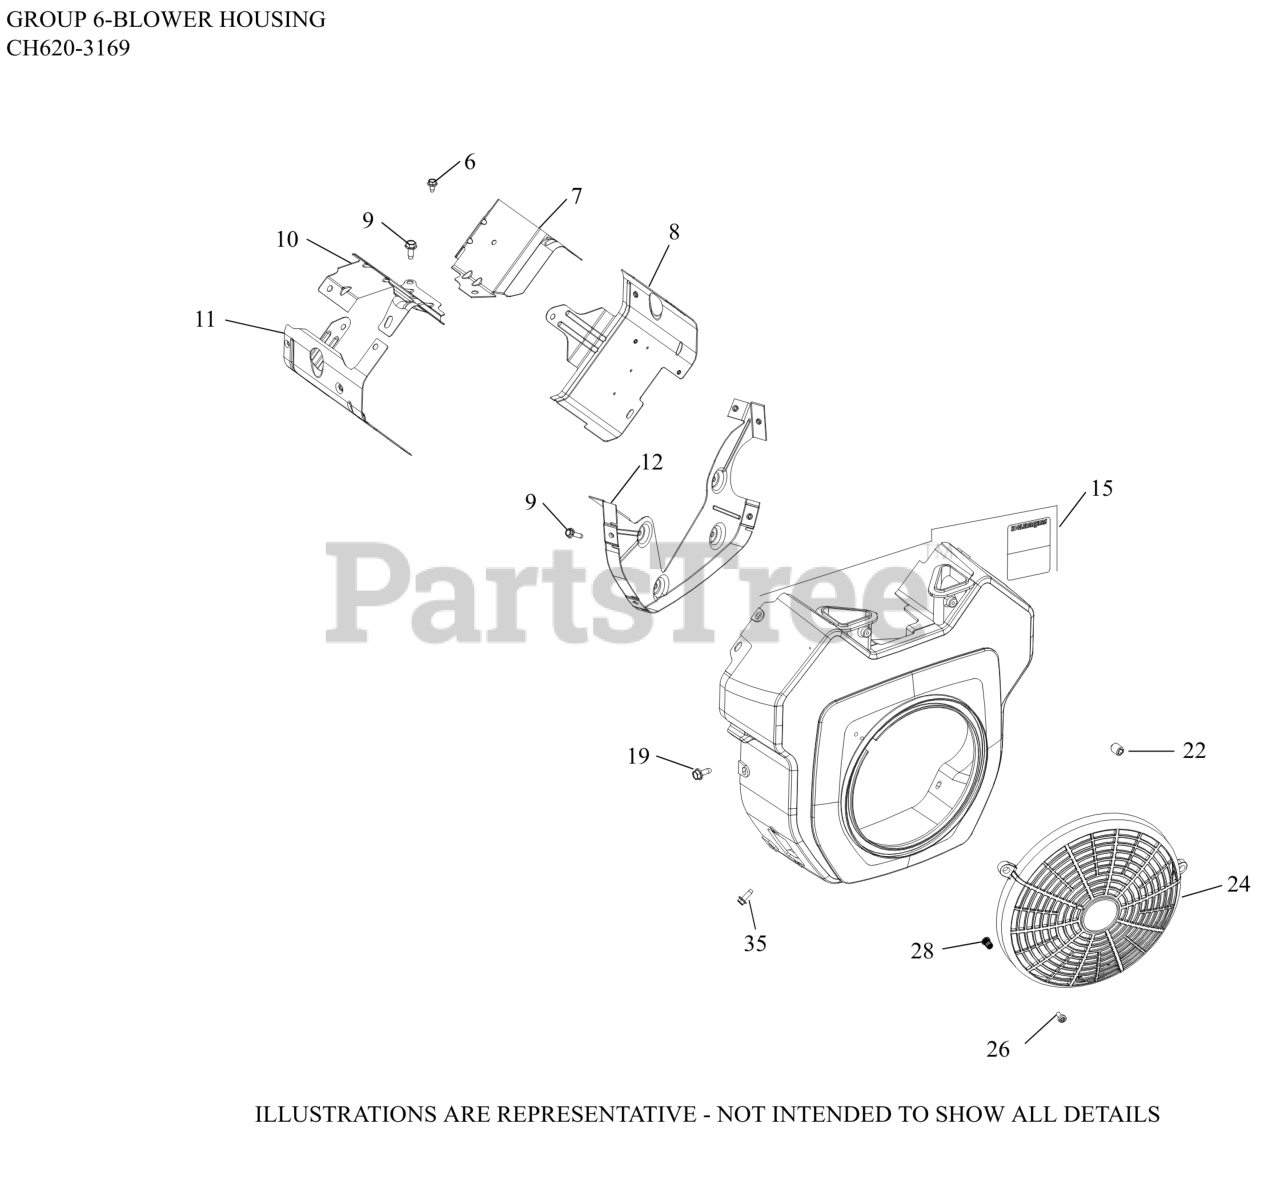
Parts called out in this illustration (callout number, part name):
6	SCREW, THREAD FORMING
7	BAFFLE, VALLEY #1 CYLINDER
8	KIT, CYL BAFFEL #1 SIDE
9	SCREW, THREAD FORMING
10	BAFFLE, VALLEY #2 CYLINDER
11	BAFFLE, LEFT BARREL
12	KIT, BACKING PLATE
15	HOUSING, BLOWER
15	KIT, BLOWER HOUSING
19	SCREW, THREAD FORMING
22	SCREW, THREAD FORMING
24	KIT, FIXED GUARD
26	SCREW, SEMS
28	INSERT, THREADED (M5)
35	SCREW, THREAD FORMING
